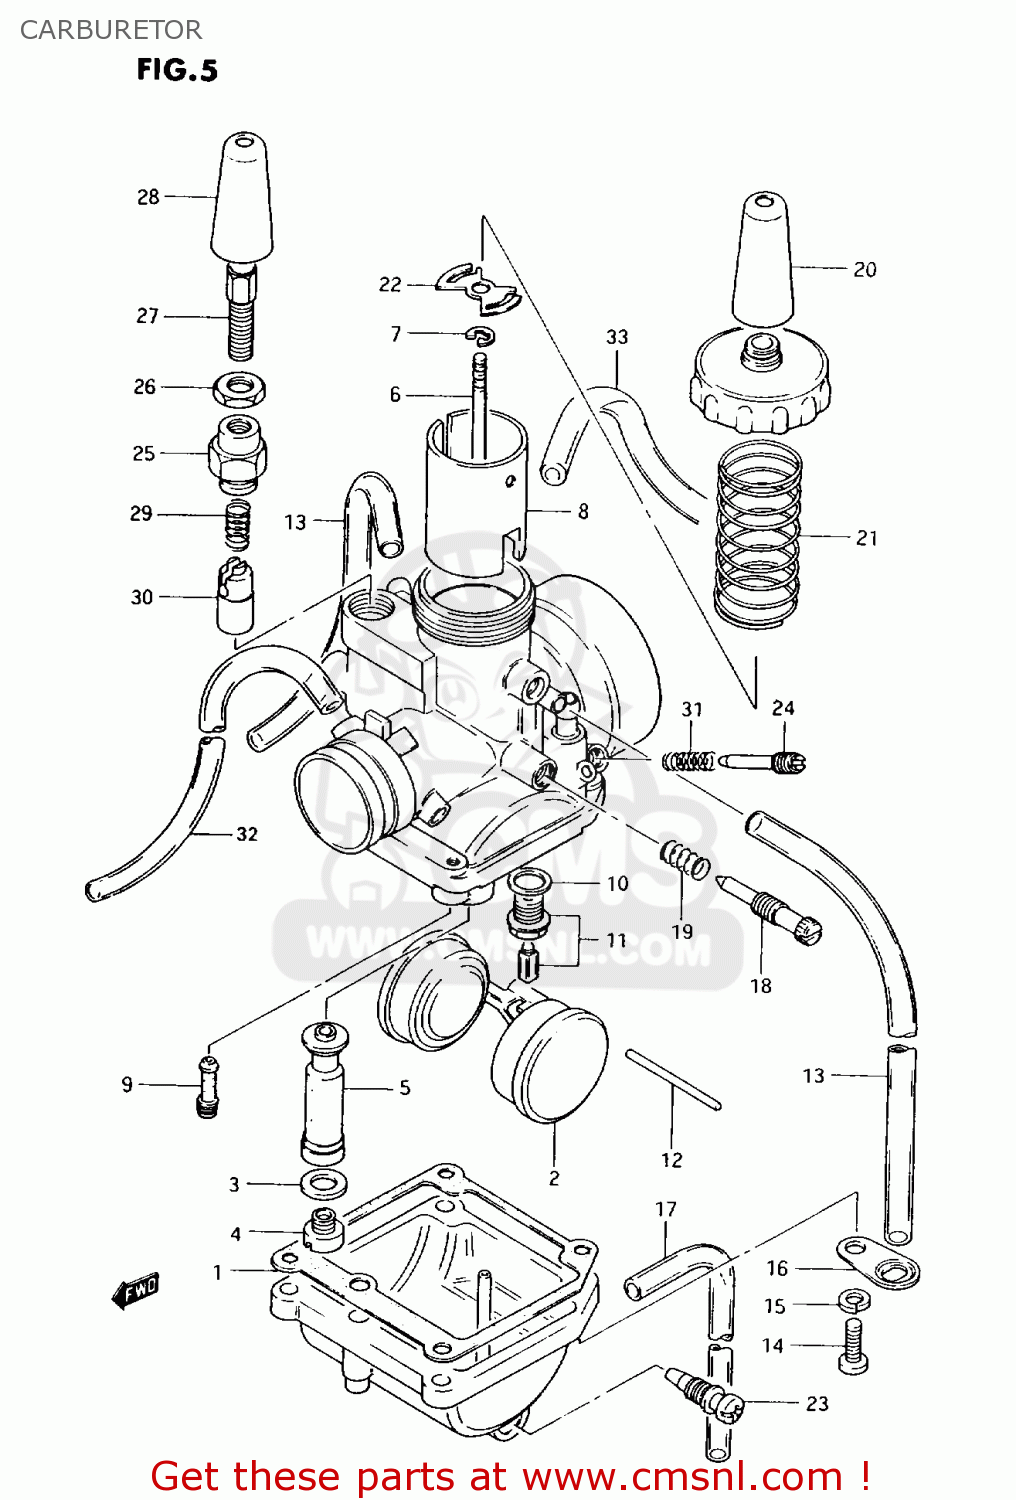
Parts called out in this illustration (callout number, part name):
1	GASKET,FLOAT CHAMBER (NAS)
2	FLOAT
3	WASHER,NEEDLE NOZZLE
4	JET,MAIN(90)
5	JET,NEEDLE(O-8)
6	NEEDLE,JET
7	CLIP
8	VALVE,THROTTLE(CA:1.5)
9	JET,PILOT
10	GASKET,NEEDLE VALVE (NAS)
11	VALVE ASSY,NEEDLE
12	PIN,FLOAT
13	HOSE(3X5X600)
14	SCREW
15	WASHER,LOCK
16	PLATE
17	HOSE(3X5X650)
18	SCREW,THROTTLE STOP
19	SPRING,THROTTLE SCREW
20	CAP,CABLE ADJUSTER
21	SPRING,THROTTLE VALVE
22	STOPPER,NEEDLE CLIP
23	PLUG,DRAIN
24	SCREW,PILOT AIR
25	CAP,STARTER PLUNGER
26	NUT
27	ADJUSTER,CABLE
28	CAP,CABLE ADJUSTER
29	SPRING
30	PLUNGER,STARTER
31	SPRING
32	HOSE(2.5X7X600)
33	HOSE(3.5X7.5X600)
